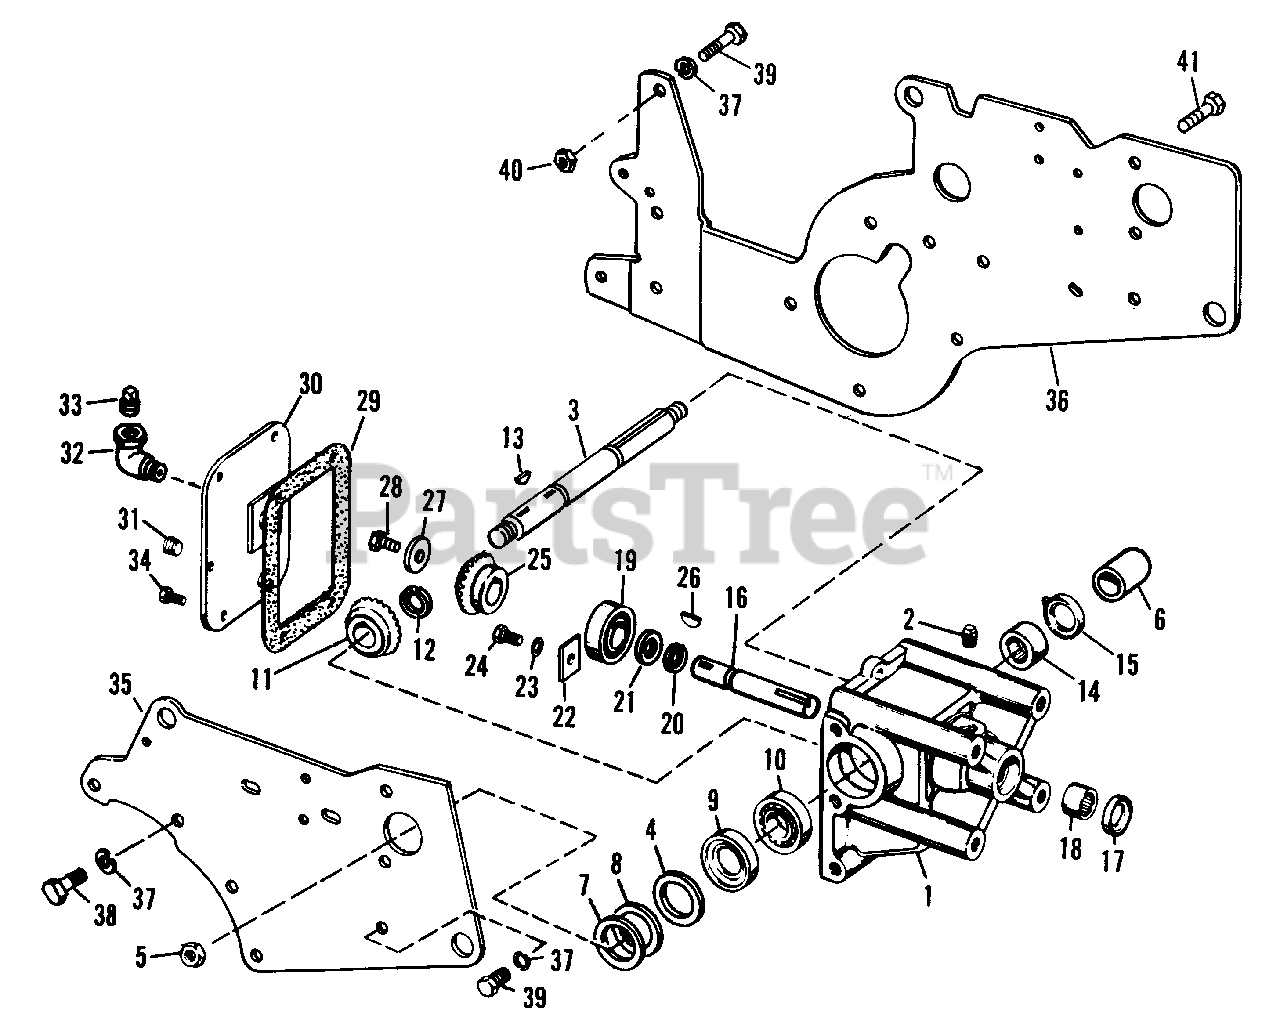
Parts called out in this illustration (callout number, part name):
1	Bevel Gear Housing, w/Bearings
2	Pipe Plug
3	Driven Shaft
5	Hex Jam Nut
7	Shim (As Required)
10	Ball Bearing
11	Bevel Driven Gear
12	Retaining Ring
14	Needle Bearing
16	Drive Shaft
18	Needle Bearing
19	Ball Bearing
20	Retaining Ring
22	Bearing Clamp Plate
23	Lock Washer, 5/16"
24	Hex Capscrew, 5/16"-18 x 5/8"
25	Bevel Driven Gear
28	Hex Capscrew, 5/16"-18 x 3/4"
30	Housing Cover Assembly
31	Pipe Plug
32	Street Elbow
33	Pipe Plug
34	Hex Cap Screw, 1/4"-20 x 5/8"
35	R.H. Side Plate
36	L.H. Side Plate
37	Lock Washer, 7/16"
38	Hex Cap Screw, 7/16"-14 x 1"
39	Hex Cap Screw, 7/16"-14 x 1-1/4"
40	Full Hex Nut, 7/16"-14
41	Hex Cap Screw, 7/16"-14 x 1-1/4"
